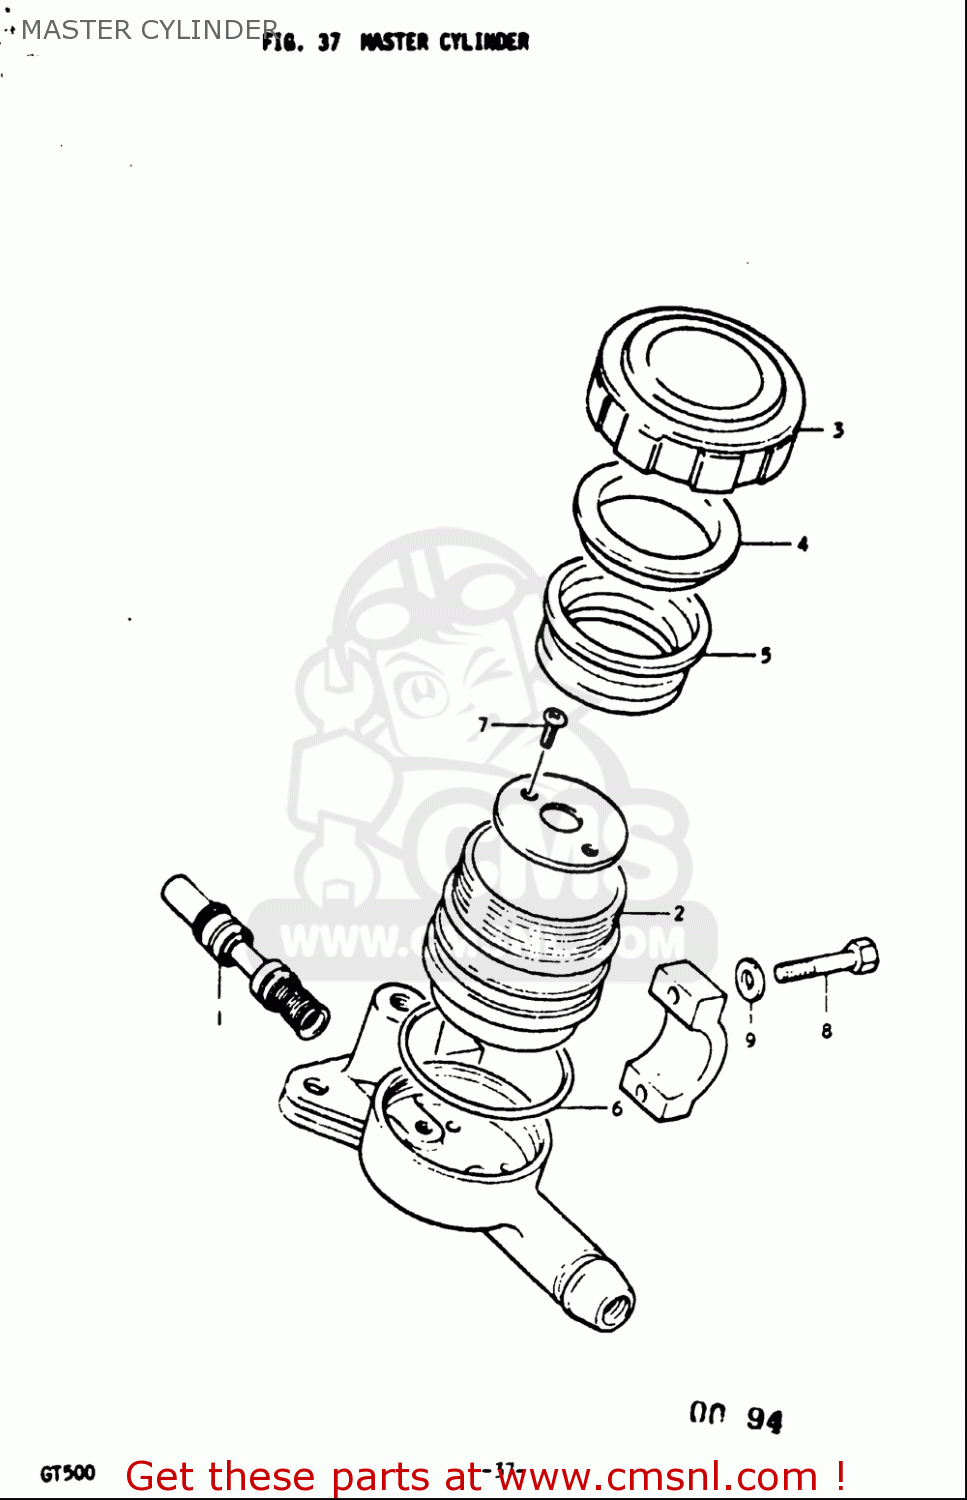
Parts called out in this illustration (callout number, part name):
1	PISTON & CUP SET
2	RESERVOIR
4	PLATE
5	DIAPHRAGM
6	O RING
8	BOLT
9	WASHER
